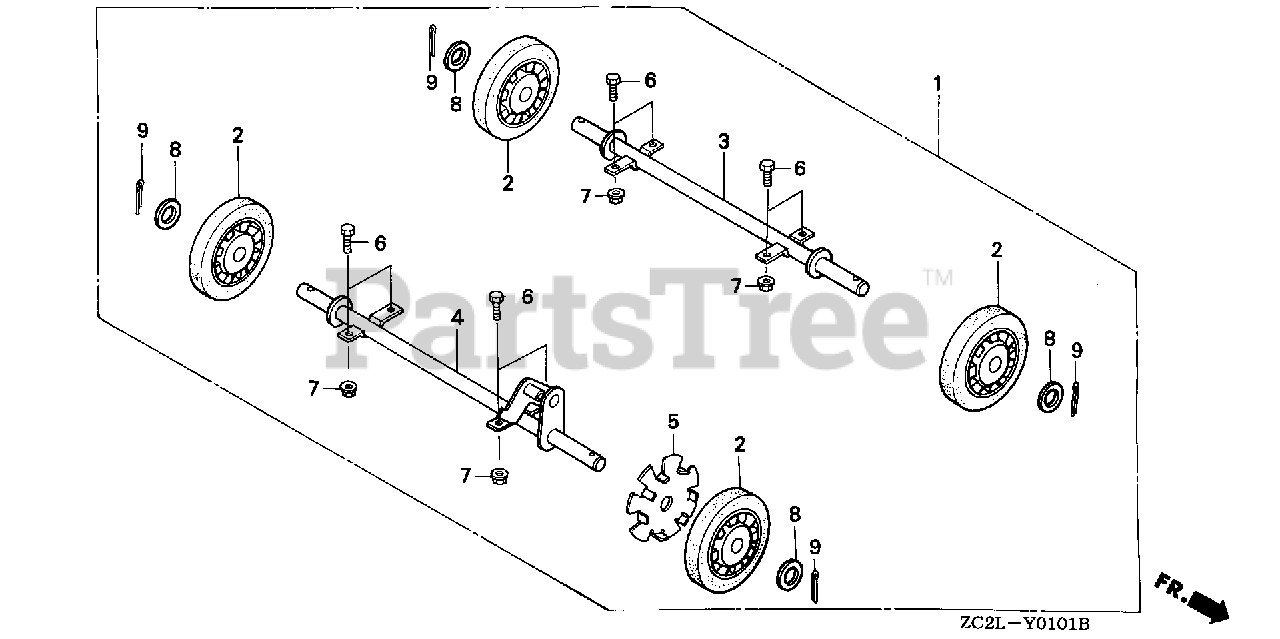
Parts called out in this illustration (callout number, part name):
1	WHEEL KIT (4-WHEELS)
2	WHEEL
3	SHAFT, R. WHEEL
4	SHAFT, L. WHEEL
5	PLATE, LOCK
6	BOLT, HEX. (8X16)
7	NUT, FLANGE (8MM)
8	WASHER, PLAIN (20MM)
9	PIN, SPLIT (4.0X28)
9	PIN, SPLIT (4.0X30)
